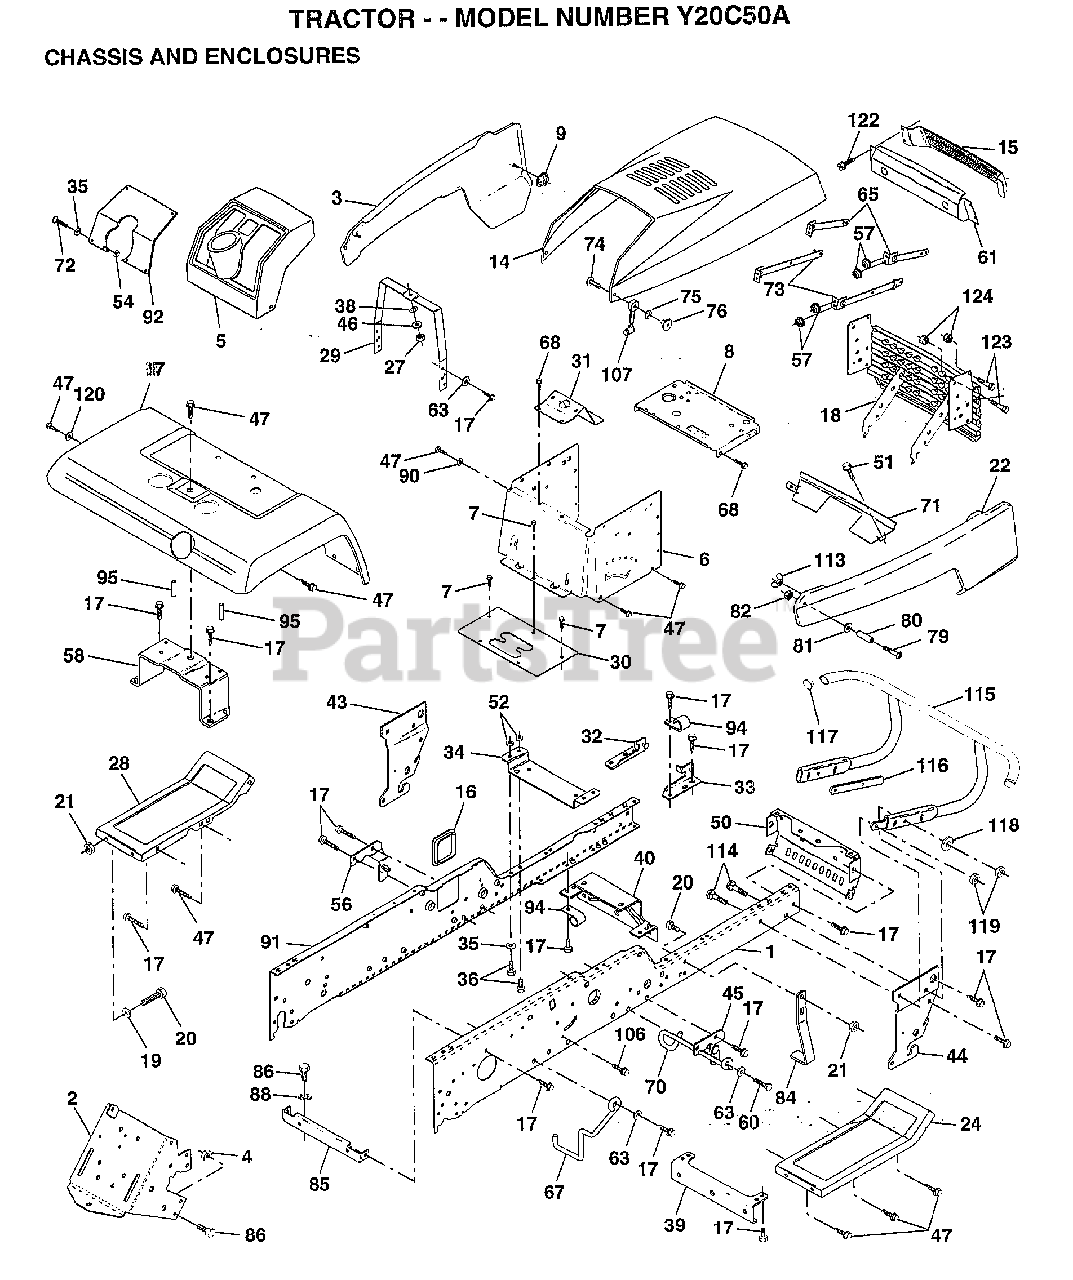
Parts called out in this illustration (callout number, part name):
2	DRAWBAR GT
4	NUT.7/16
5	DASHBOARD BLACK
6	DASH.1PC.LOWER
7	SCREW
8	SUPPORT.DASH.BTRY
9	PAL NUT LT
15	LENS.BAR.CLEAR
16	COVER ACCESS
17	SCREW
19	WASHER
20	BOLT
22	PANEL SIDE RH
23	SCREW GTV
24	FOOTREST.RH.LT/GT
28	FOOTREST.LH.LT/GT
29	DASH.SUPT.YP/HUSQ
30	SADDLE.SCR.6SP
31	BRAKET.SUPT.STEER
32	BRACKET ASM FRAME
33	BRACKET ASM FRAME
34	BRACKET.ENG.SUPT.
35	WASHER
36	BOLT
37	FENDER
38	WASHER PM
39	BRACKET.AXLE.FRT.
43	BRACKET.SUS.FT.LH
44	BRACKET.SUS.FT.RH
46	LOCKWASHER
47	SCREW LT
50	BRACKET.CHASSIS.
51	SCREW CRT
57	NUT
58	BRKT.ASM.FENDER
60	SCREW
61	BEZEL.ASM.
62	BOLT D
63	WASHER
65	STRAP.ASM.HINGE.
67	GUIDE BELT TRANS
68	SCREW LT
70	GUIDE.BELT.MID.SP
71	STRAP.GRILLE.PNT.
72	SCREW
73	STRAP.ASM.HINGE.R
74	SCREW
75	LOCKWASHER
76	WELDNUT
79	SCREW
80	SPACER LT
81	WASHER
84	STOP.OVER.CENTER
85	BRACKET.SUPT.TRAN
86	BOLT
88	LOCKWASHER
90	LOCKWASHER
92	PLATE YP SLKSCR
94	CLIP GTV
95	NUT-PUSH YT
107	HOOD LATCH T
114	BOLT.3/8-14X1.25
115	BUMPER.ASM.W/PY
116	BRACKET.EXT.BUMP.
117	PLUG.PLASTIC
118	WASHER
120	WASHER HYT
124	NUT
